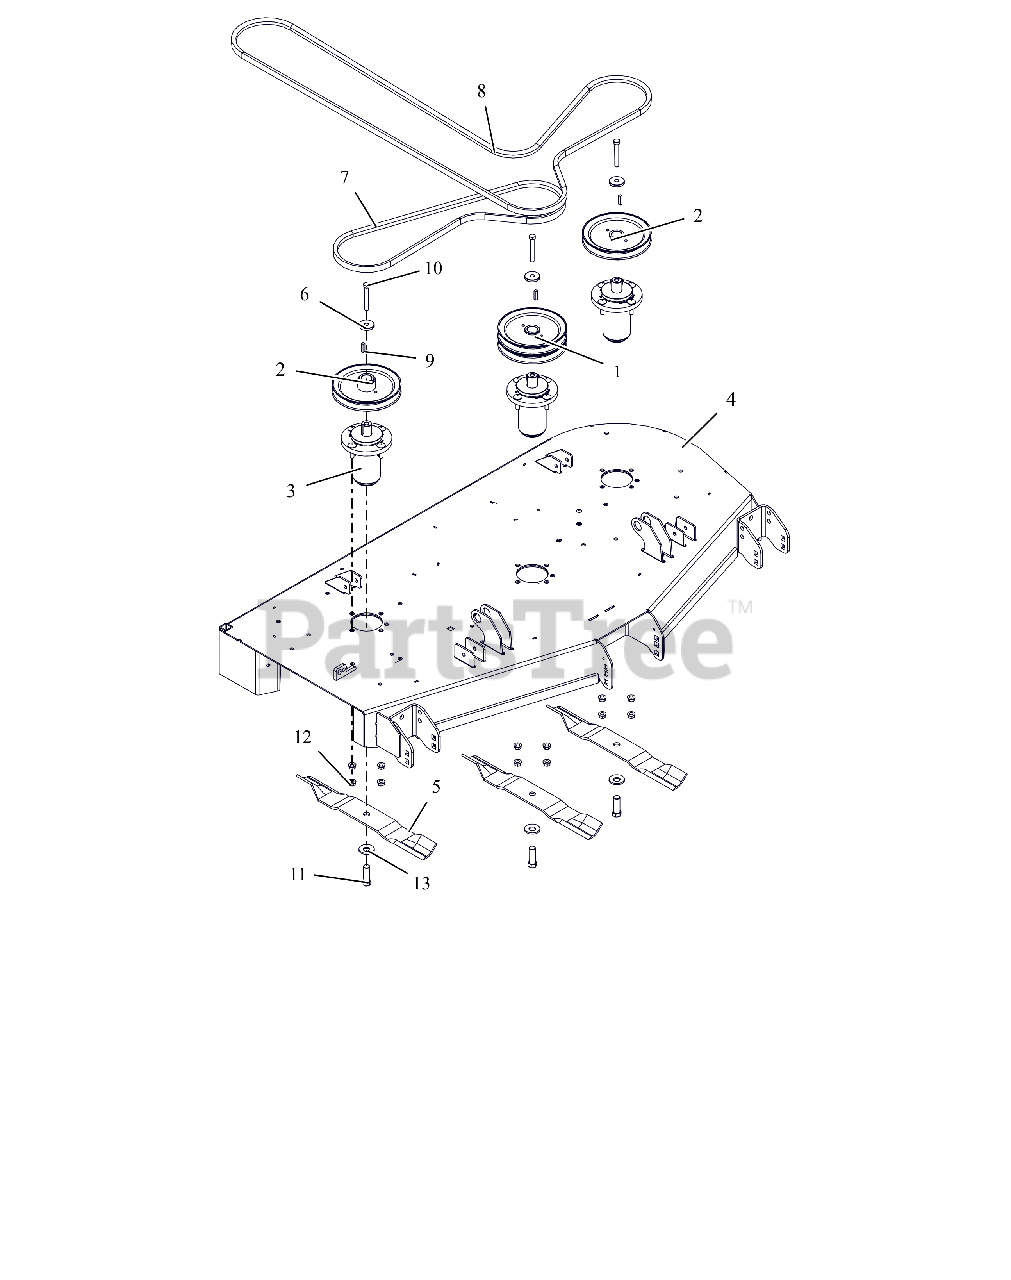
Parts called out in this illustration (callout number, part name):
1	PULLEY, DOUBLE-1"ID X 6.75"OD
2	PULLEY, V-1" ID X 6.75" OD
3	ASM, MAINT FREE ALUM SPINDLE
4	KIT,DECK-52" W/DECALS-GRAVELY
5	BLADE, 18"
6	RETAINER, SHEAVE
7	V-BELT, B-COGGED
8	V-BELT, HB SECTION
9	KEY, SQ .25X.25X1.00 RC 40-50
10	BLT, HEX .38-16X2.75 G8 ZCC
11	BLT, HEX .62-18X1.75 G8 ZCC
12	NUT-LK-CTR-FLG .375-16 GF ZCC
13	WSHR-BLVL .669X1.535X.138
